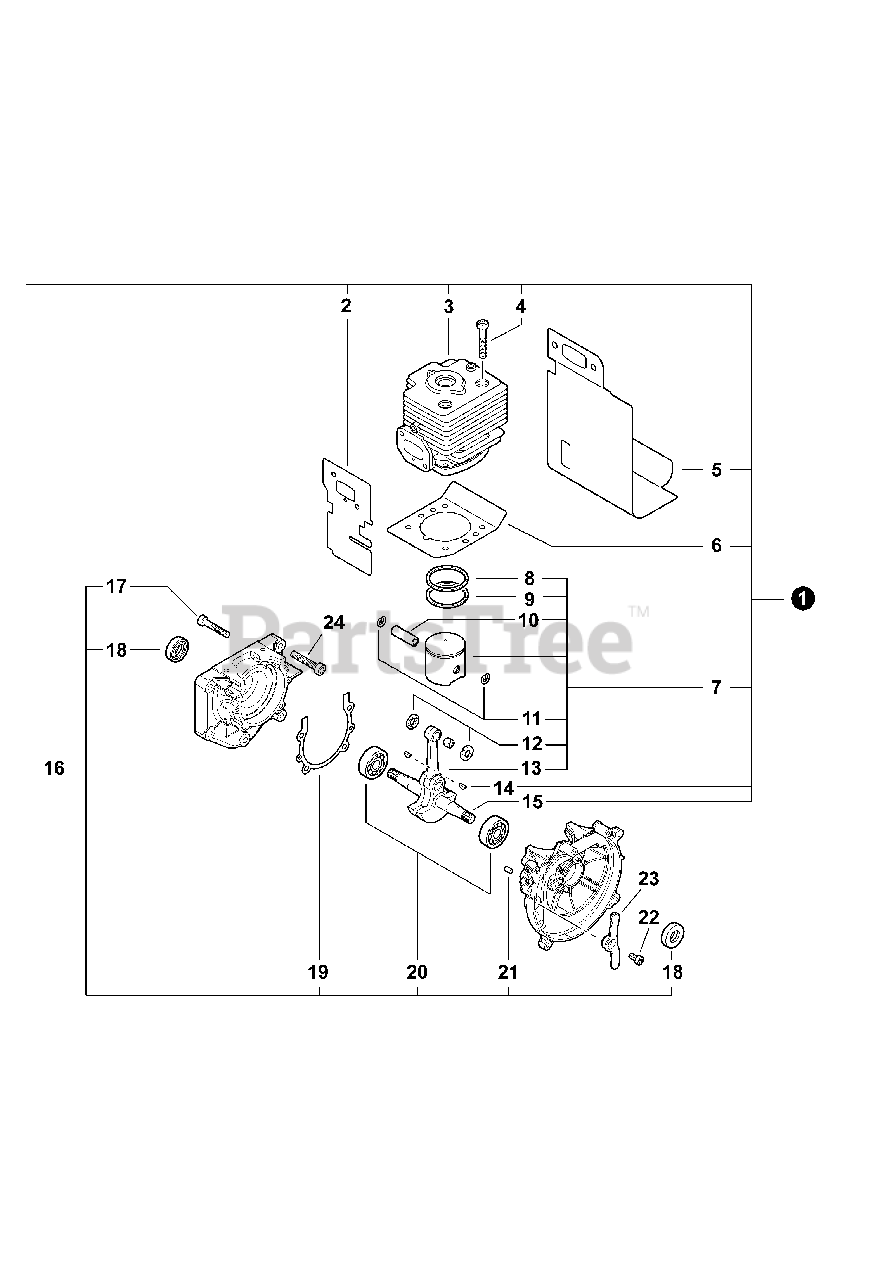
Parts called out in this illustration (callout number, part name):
1	SHORT BLOCK -- SB1099
2	SHIELD, INTAKE
3	CYLINDER
4	SCREW - 5×25
5	SHIELD, EXHAUST
6	GASKET, CYLINDER
7	PISTON KIT
8	RING, PISTON
9	RING, PISTON
10	PIN, PISTON
11	RING, RETAINING - 8
12	WASHER - 10
13	BEARING, NEEDLE - 10
14	KEY - 3×14
15	CRANKSHAFT ASSY
16	CRANKCASE KIT
17	SCREW - 5×30
18	SEAL, OIL
19	GASKET, CRANKCASE
20	BEARING, BALL - 6302
21	PIN, LOCATING
22	SCREW - 5×10
23	COVER, DUST
24	SCREW - 6×30
